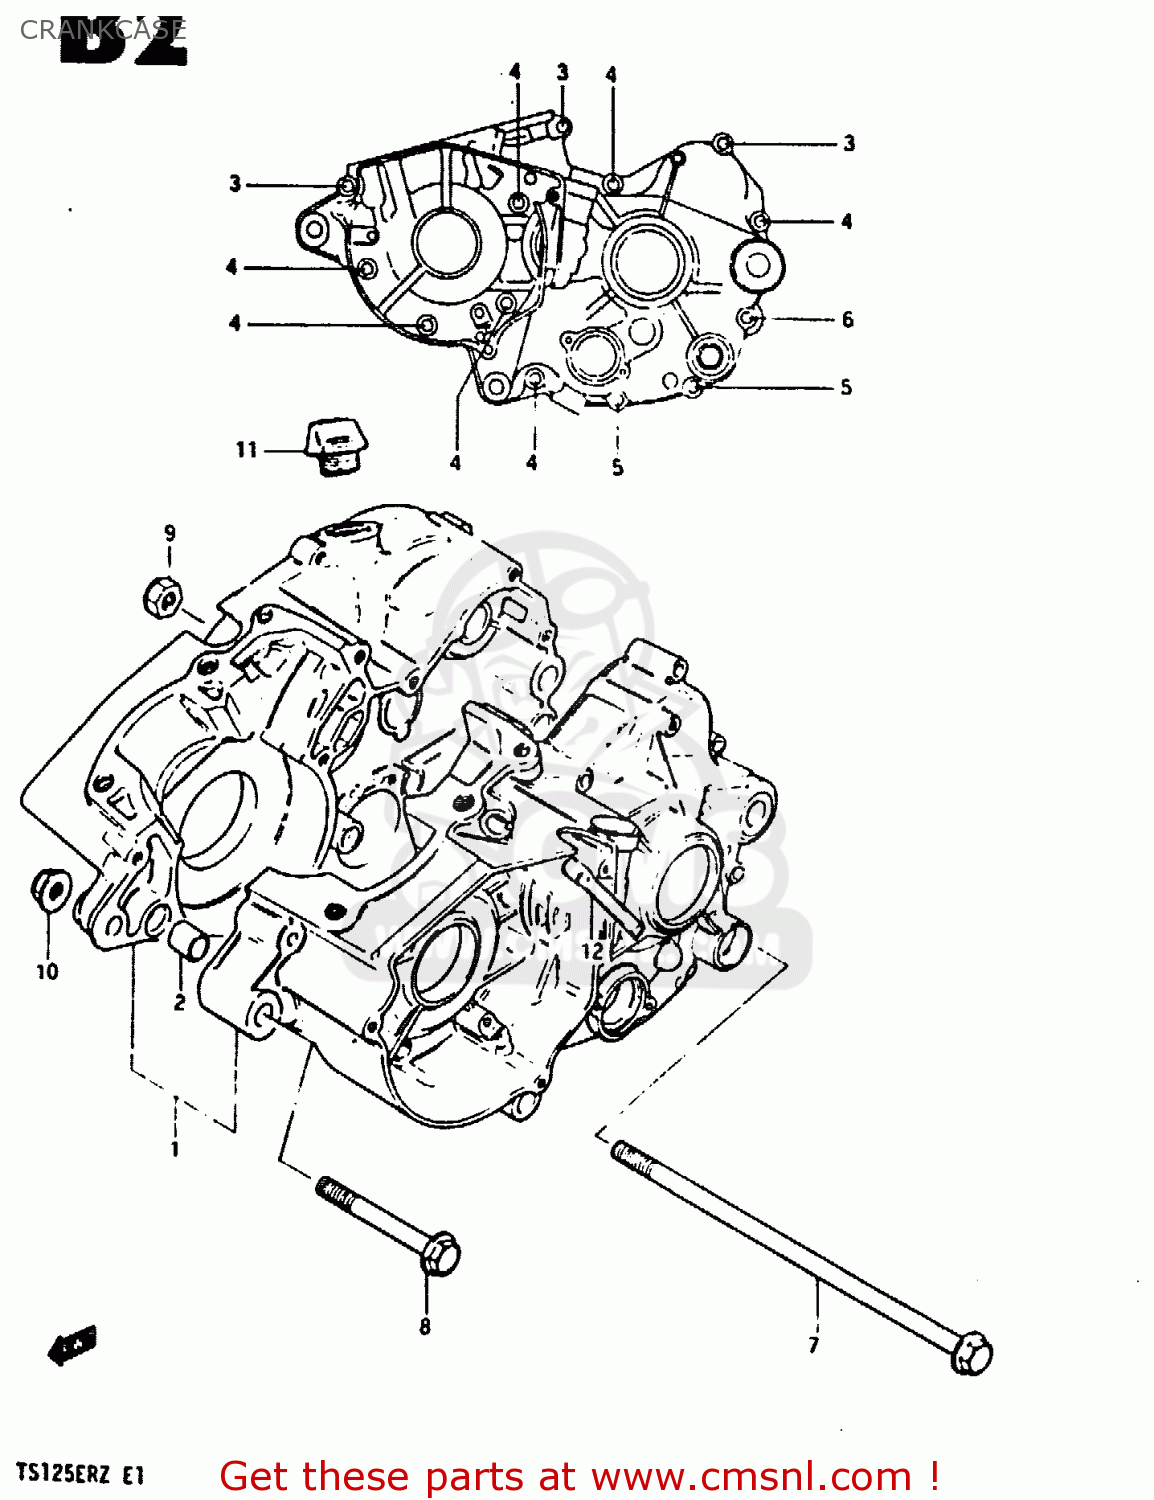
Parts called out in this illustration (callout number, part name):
1	CRANKCASE SET
2	PIN
3	SCREW
4	SCREW (6X45)
5	SCREW 6X65
6	SCREW 6X80
7	BOLT(8X200)
8	BOLT 8X65
9	NUT
10	NUT
11	PLUG,OIL FILTER
12	HOSE, BREATER
